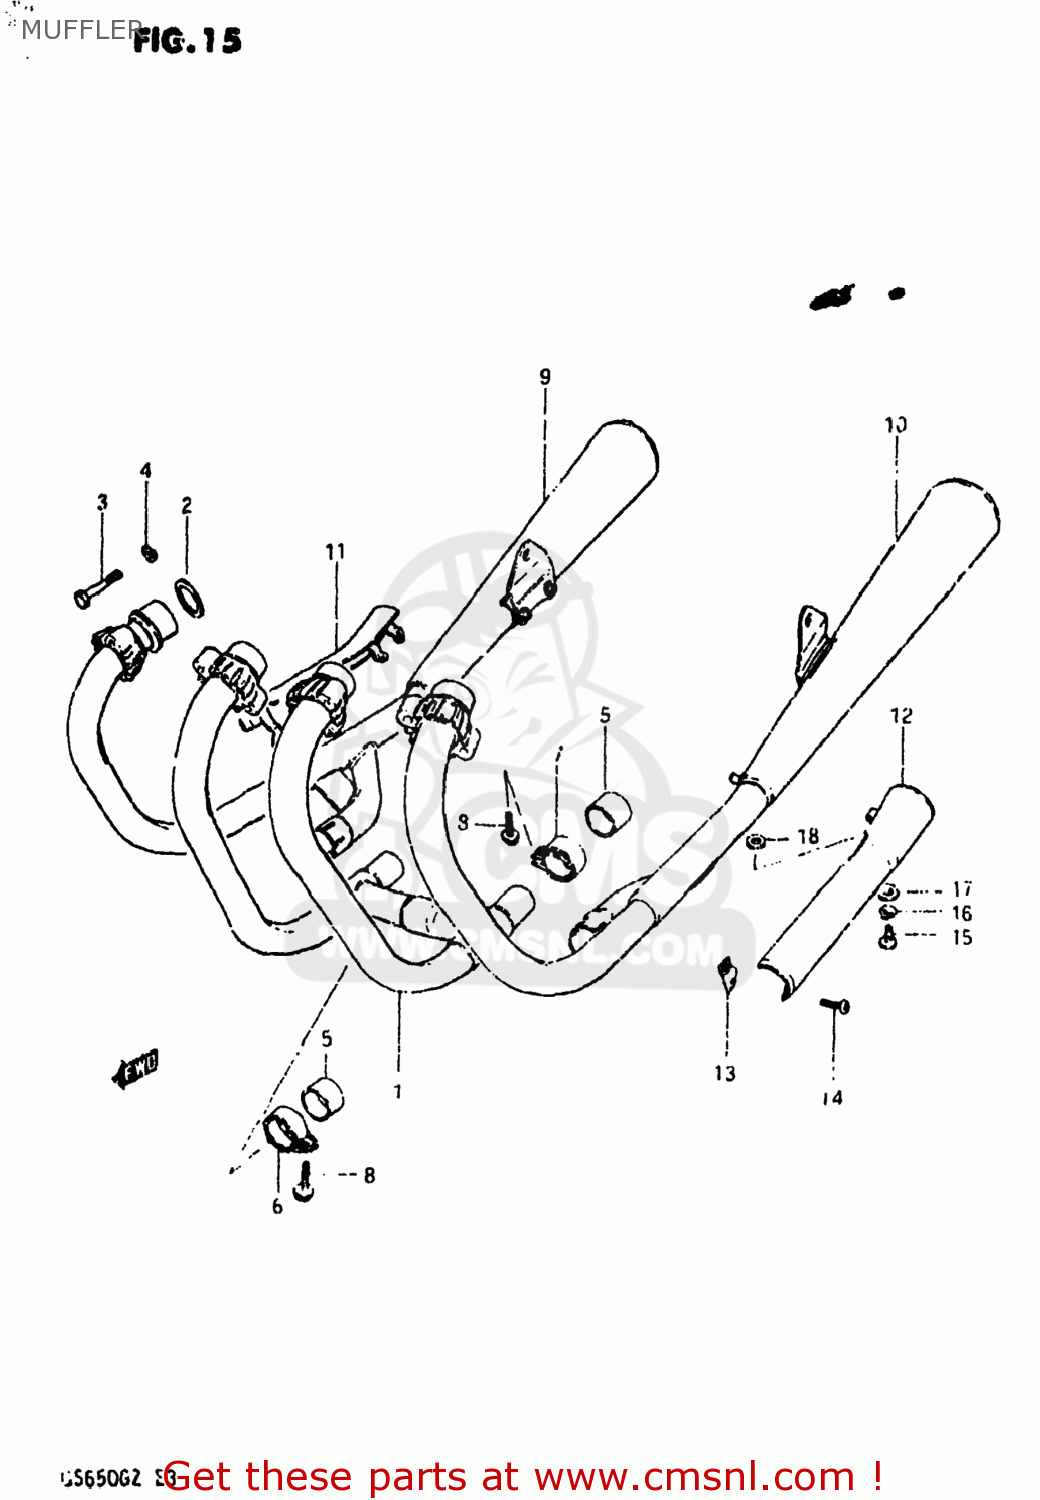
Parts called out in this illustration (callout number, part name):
1	PIPE,EXHAUST CTR
2	GASKET,EXHAUST PIPE (NAS)
3	BOLT 8X40
4	LOCK WASHER
5	CONNECTOR,MUFFLER
6	CLAMP,MUFFLER CONNECTOR,R
7	CLAMP,MUFFLER CONNECTOR,L
8	BOLT
9	MUFFLER ASSEMBLY
10	MUFFLER ASSEMBLY
11	COVER,MUFFLER,RIGHT
12	COVER,MUFFLER,LEFT
13	CLAMP,MUFFLER COVER
14	SCREW 5X20
15	SCREW 6X12
16	LOCK WASHER
17	WASHER
18	GASKET 6.2X12X1.5 (MCA)
